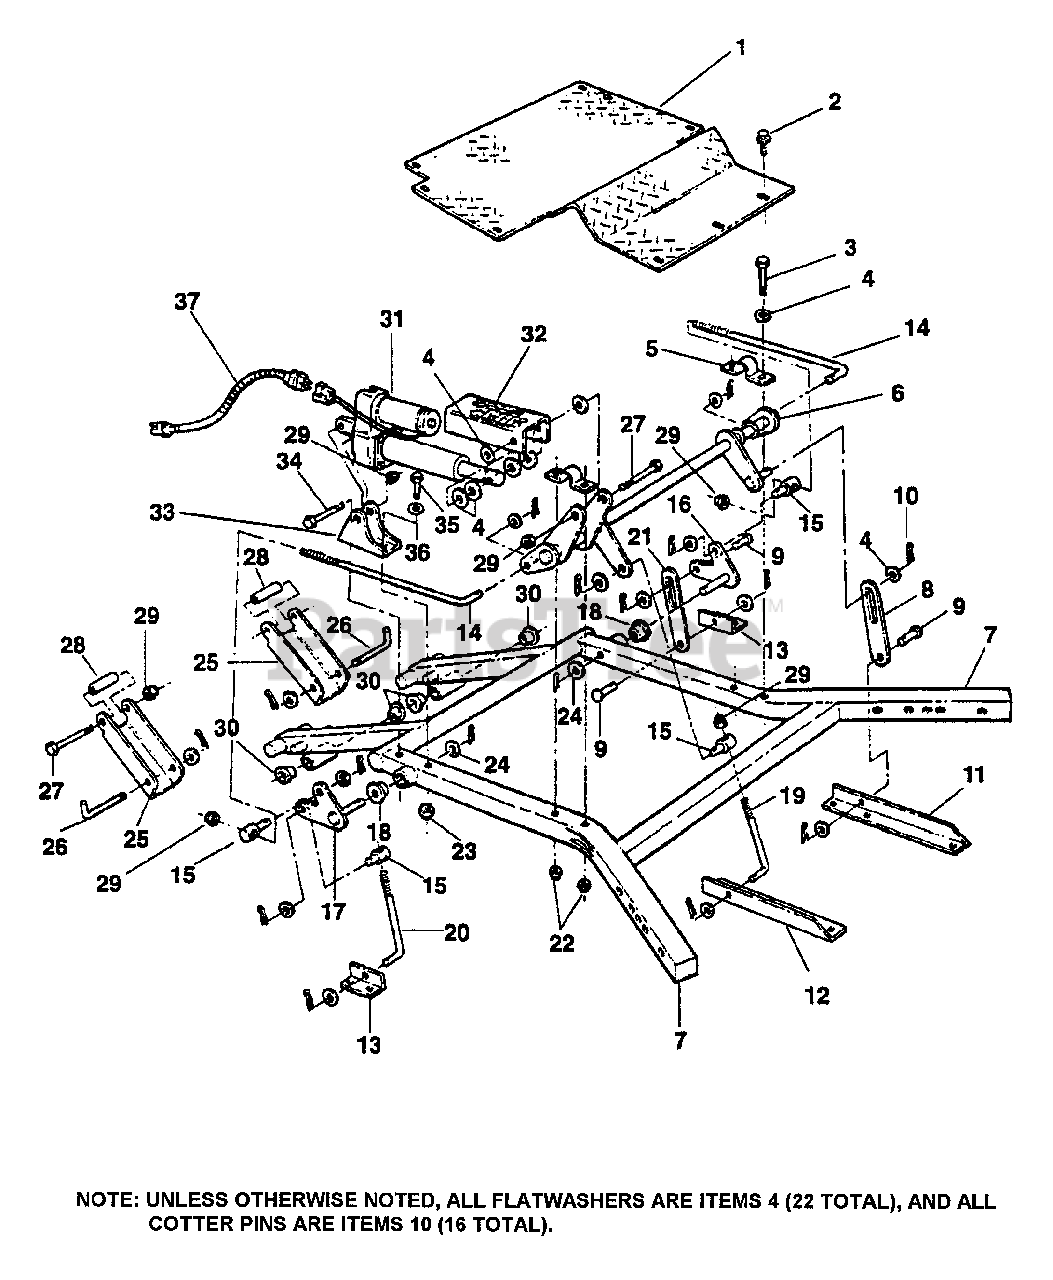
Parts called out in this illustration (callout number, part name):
1	PLATE, Diamond Tread Foot
2	SCREW, 5/16-18 x 5/8" Hex Washer Head, Self-Tapping Swage
3	BOLT, 5/16-18 X 2-1/2" GD5 YZ
4	WASHER, .531 x1.062 x.121 SAE Flat
5	BRACKET, Deck Lift Hanger
6	ARM, Front Lift (Weldment)
7	FRAME, Deck (Weldment)
8	BAR, 7" Lift
9	PIN, 1/2 x 1 1/8" Clevis (YZ)
10	PIN, 5/32 x 1" Cotter
11	ANGLE, Front Deck Mounting (L.H.)
12	ANGLE, Front Deck Mounting (R.H.)
13	BRACKET, Deck Lift, Rear
14	ROD, Timing, 1/2" Threaded
15	SWIVEL, .50 Thru Hole
16	ARM, Rear Bellcrank (L.H.) (Weldment)
17	ARM, Rear Bellcrank (R.H.) (Weldment)
18	BEARING, .75 I.D.
19	J-BOLT, 1/2" Dia. x 8 1/2" Long (Front)
20	J-BOLT, 1/2" Dia. x 7" Long (Rear)
21	BAR, 5.62 Lift
22	NUT, 5/16-18 HEX NYLON LOCK
23	NUT, 3/8-16 HEX NYLON LOCK
24	WASHER, 13/16 x 1 15/32" (HS)
25	CHANNEL, Deck Stabilizer
26	J-BOLT, Deck Attachment
27	BOLT, 1/2-13 x 4" Hex (HO)
28	SLEEVE, Stabilizer
29	NUT, 1/2-13 HEX NYLON LOCK
30	BUSHING, Suspension
31	LINEAR ACTUATOR, 1000 Lbs., 4" Stroke
32	INDICATOR, Height Of Cut
33	BRACKET, Actuator Anchor
34	SCREW, 1/2 UNC x 2.5 Hex Head Cap (Black Phosphate)
35	BOLT, 3/8-16 X 2-1/2" GD5 CZ
36	WASHER, 3/8" Flat
37	WIRE HARNESS, Deck Lift
